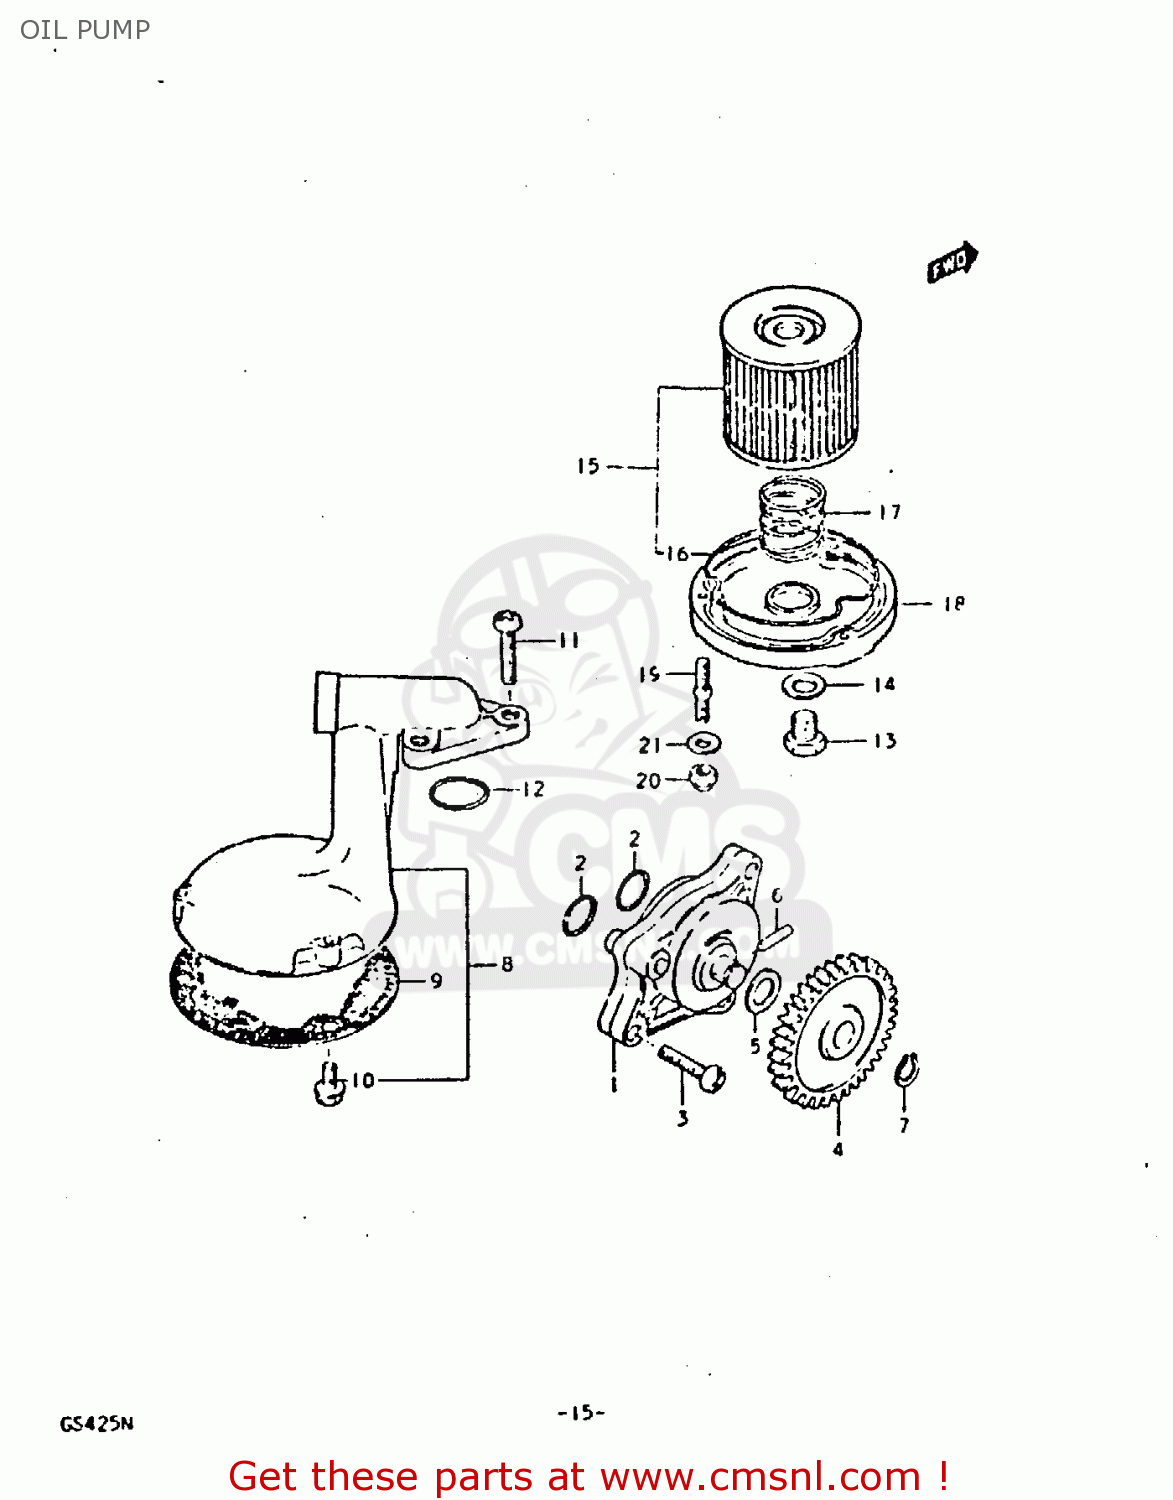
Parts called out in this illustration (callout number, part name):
1	PUMP ASSEMBLY,OIL
2	O RING(D:1.9,ID:13)
3	SCREW
4	GEAR,OIL PUMP DRIVEN
5	SHIM
6	PIN(4X15.8)
7	CIRCLIP
8	STRAINER,ENGINE OIL
9	NET
10	BOLT
11	SCREW
12	O RING(D:2.4,ID:15.8)
13	PLUG
14	GASKET(14X19.2X2) (NAS)
15	ENGINE OIL FILTER SET
16	O RING,OIL FILTER CHAMBER CAP
17	SPRING
18	CAP,OIL FILTER
19	STUD 6X20
20	NUT
21	LOCK WASHER
